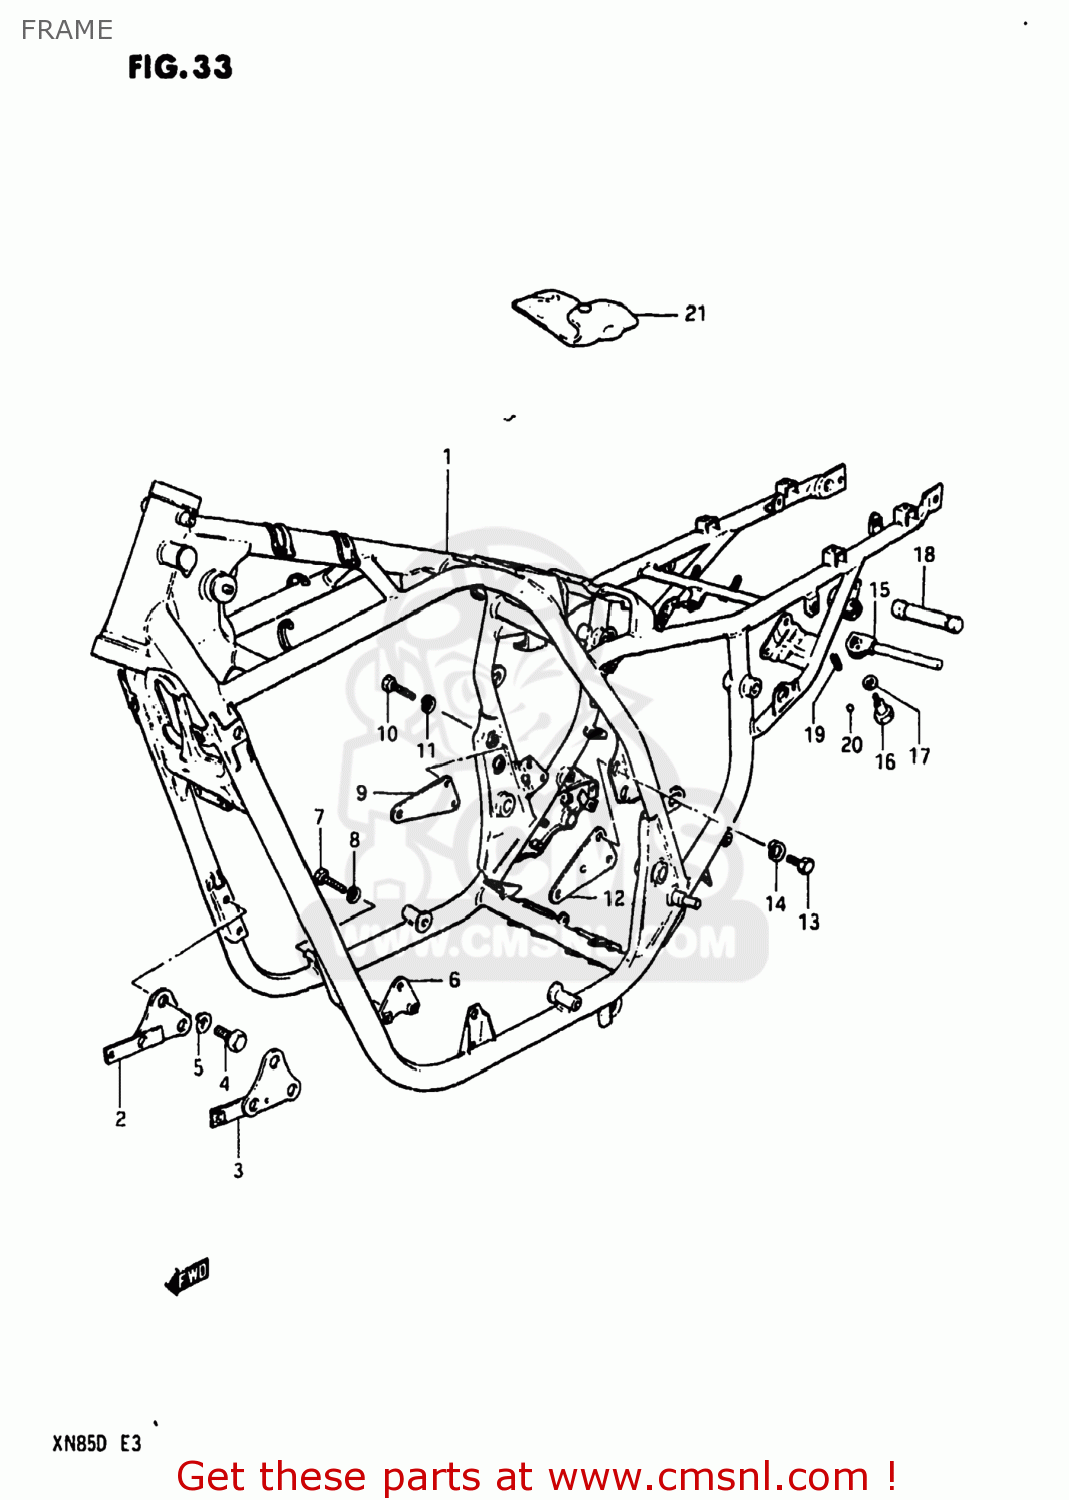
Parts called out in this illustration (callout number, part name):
1	FRAME
2	PLATE COMP,ENGINE MOUNTING
3	PLATE,ENGINE MOUNTING
4	BOLT
5	LOCK WASHER
6	PLATE,ENGINE MOUNTING
7	BOLT 8X50
8	LOCK WASHER
9	PLATE,ENGINE MOUNTING
10	BOLT 8X50
11	LOCK WASHER
12	PLATE,ENGINE MOUNTING
13	BOLT
14	LOCK WASHER
15	GRIP COMP,FRAME HANDLE
16	BOLT
17	WASHER
18	RUBBER
19	SPRING
20	BALL
21	TOOL SET
